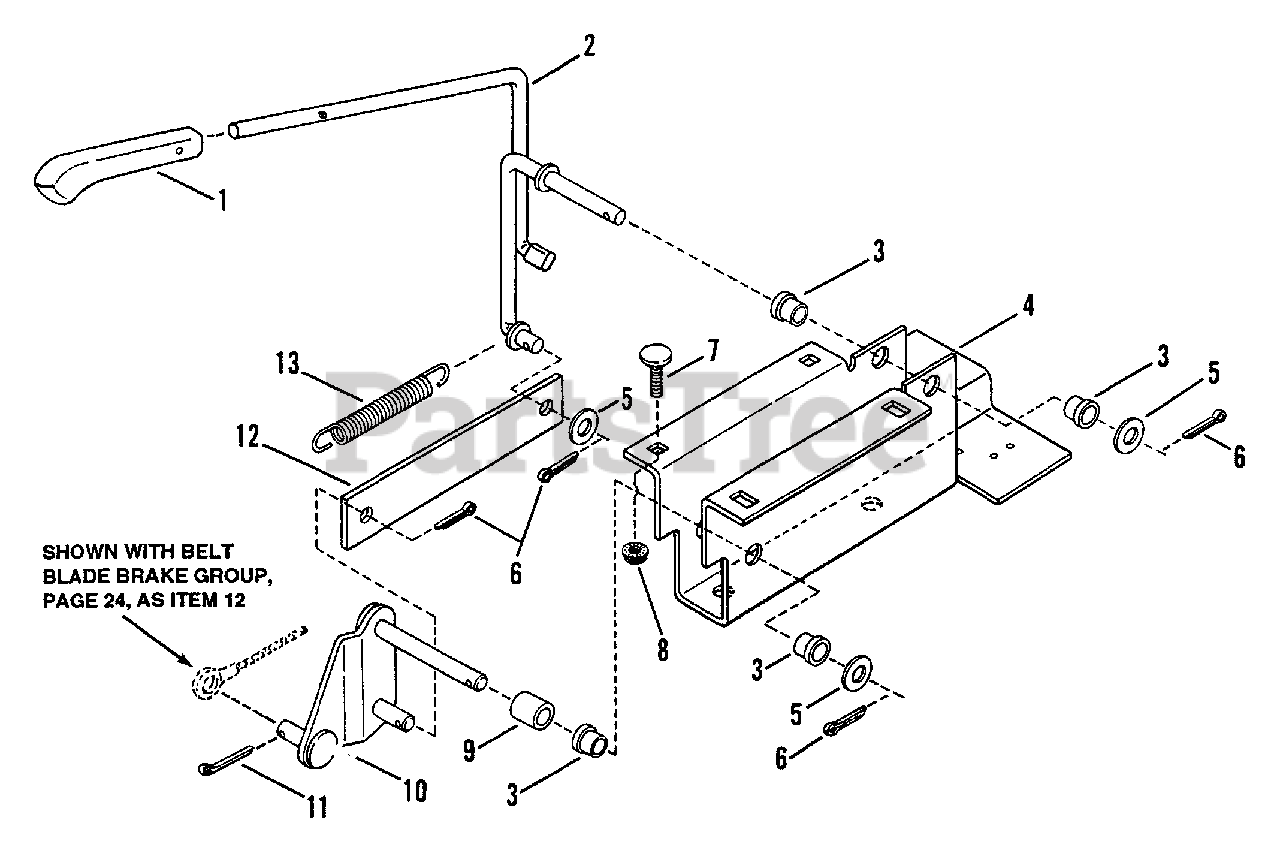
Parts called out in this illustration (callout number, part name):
1	KNOB, Handle 7/16"
2	HANDLE, Blade Engagement (No longer available, try using 7040674)
3	BUSHING
4	BRACKET, Handle
5	WASHER, 3/8 SAE YZ
6	COTTER-PIN, 3/32 x 3/4"
7	BOLT, 1/4-20 x 5/8" Flat Hd. Carriage
8	NUT, 1/4-20 Hex Flange Lock
9	SPACER .625 OD x .380 ID x .560 L
10	PIVOT ARM ASSEMBLY
11	COTTER-PIN, 3/32 x 1"
13	SPRING, Return
